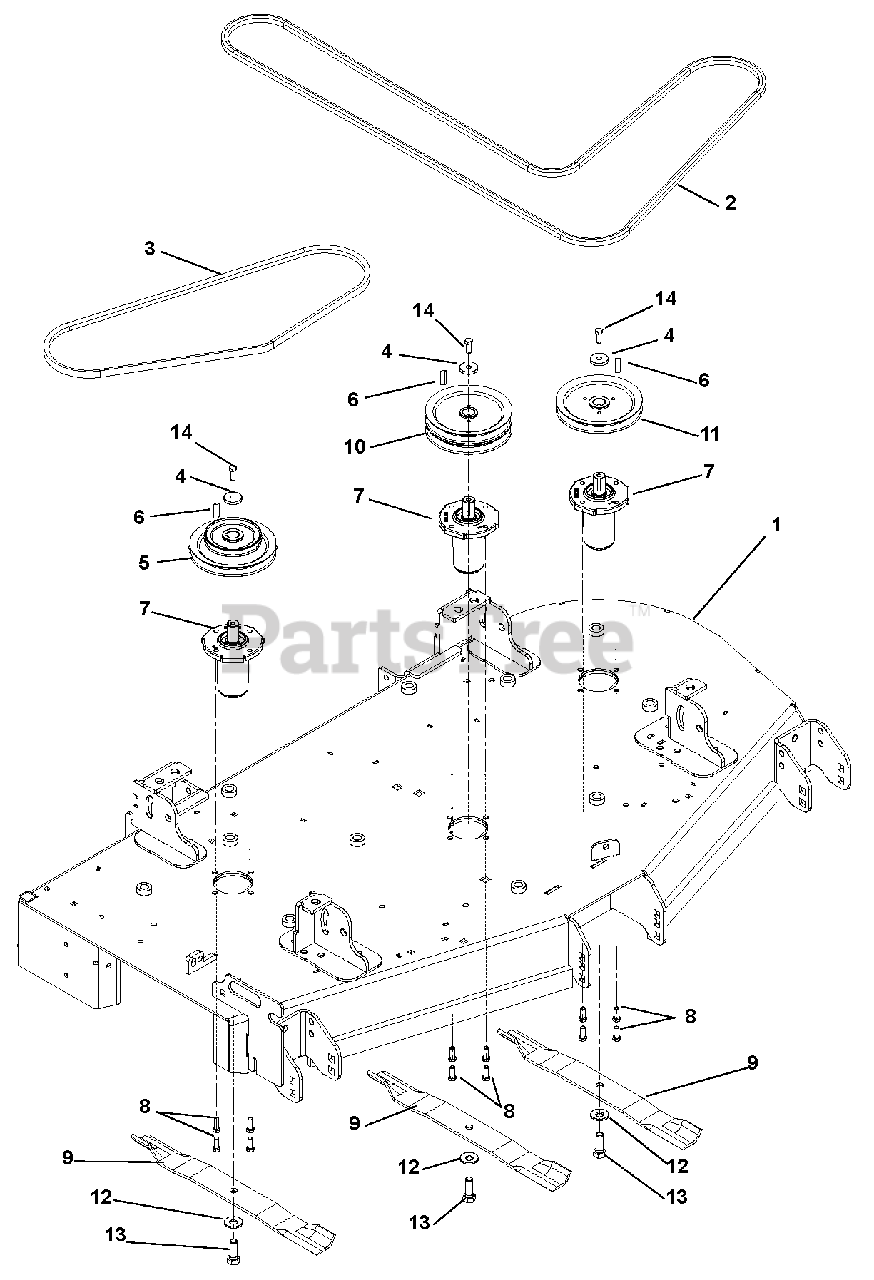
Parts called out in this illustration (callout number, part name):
1	Deck, 60" (992201, 203, 204, 198)
2	Hex Belt, BB-Wrapped Clutching (992201, 203, 204, 198)
3	V-Belt, B-Raw Edge Cogged (992201, 203, 204, 198)
4	Retainer, Sheave
5	Sheave, Double 1.0" ID x 6.75" x 4.25" OD (992201, 203, 204, 198) (Prior to SN 21000)
6	Key, Square .25 x .25 x 1.00
7	Assembly, Spindle G3500
8	Bolt, Hex .38-16 x 1.00
9	Blade, Mower (20.50") (992201, 203, 204, 198)
10	Pulley, Double 1" ID x 6.75" OD (992201, 203, 204, 198)
11	Pulley, Single 1" ID x 6.75" OD (992201, 203, 204, 198)
12	Washer, Bellville .63 x 1.625 x .14
13	Bolt, Hex .62-18 x 1.75 Grade 8
14	Bolt, Hex .38-16 x 2.75 Grade 8
